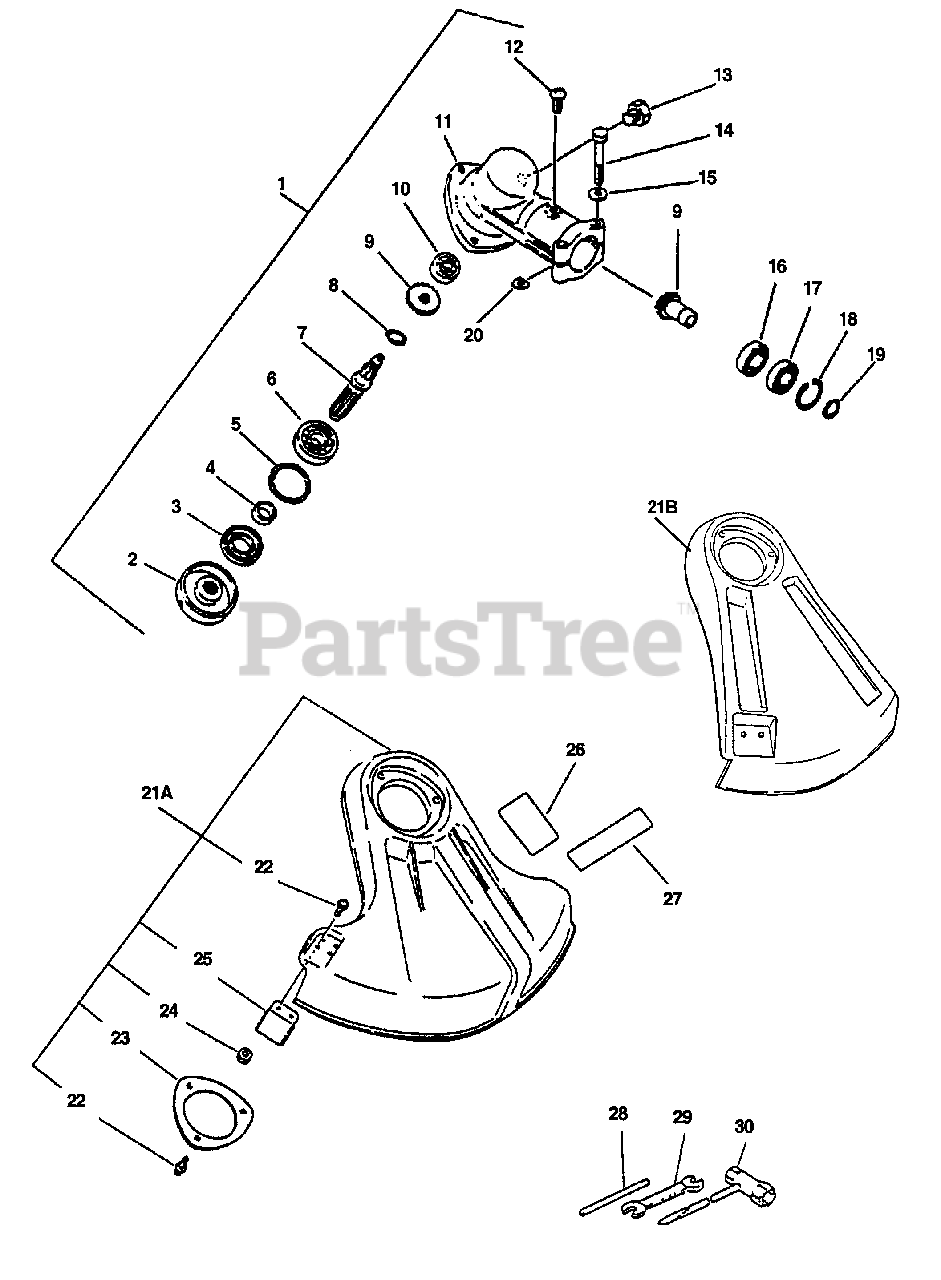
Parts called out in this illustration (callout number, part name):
1	Housing asy, gear
2	Plate, adapter (u)
5	Circlip 32
6	Bearing, ball 6201
7	Shaft, p.t.o.
8	Circlip 10
9	Gear set
10	Bearing, ball 609
11	Housing, gear
12	Screw 5x10
13	Bolt 8x8
14	Bolt 5x35
15	Washer 5
16	Bearing, ball 6900
17	Bearing, ball 6900z
18	Circlip22
19	Circlip 12
20	Washer, shim
21A	Shield asy (s/n 001001 - 519600)
21B	Shield asy (s/n519601 & up)
22	Screw 5x16
23	Bracket, shield
25	Cutter
26	Label, caution
27	Label, echo
28	Locking tool
29	Spanner 8x10
30	Wrench, w/screwdriver
